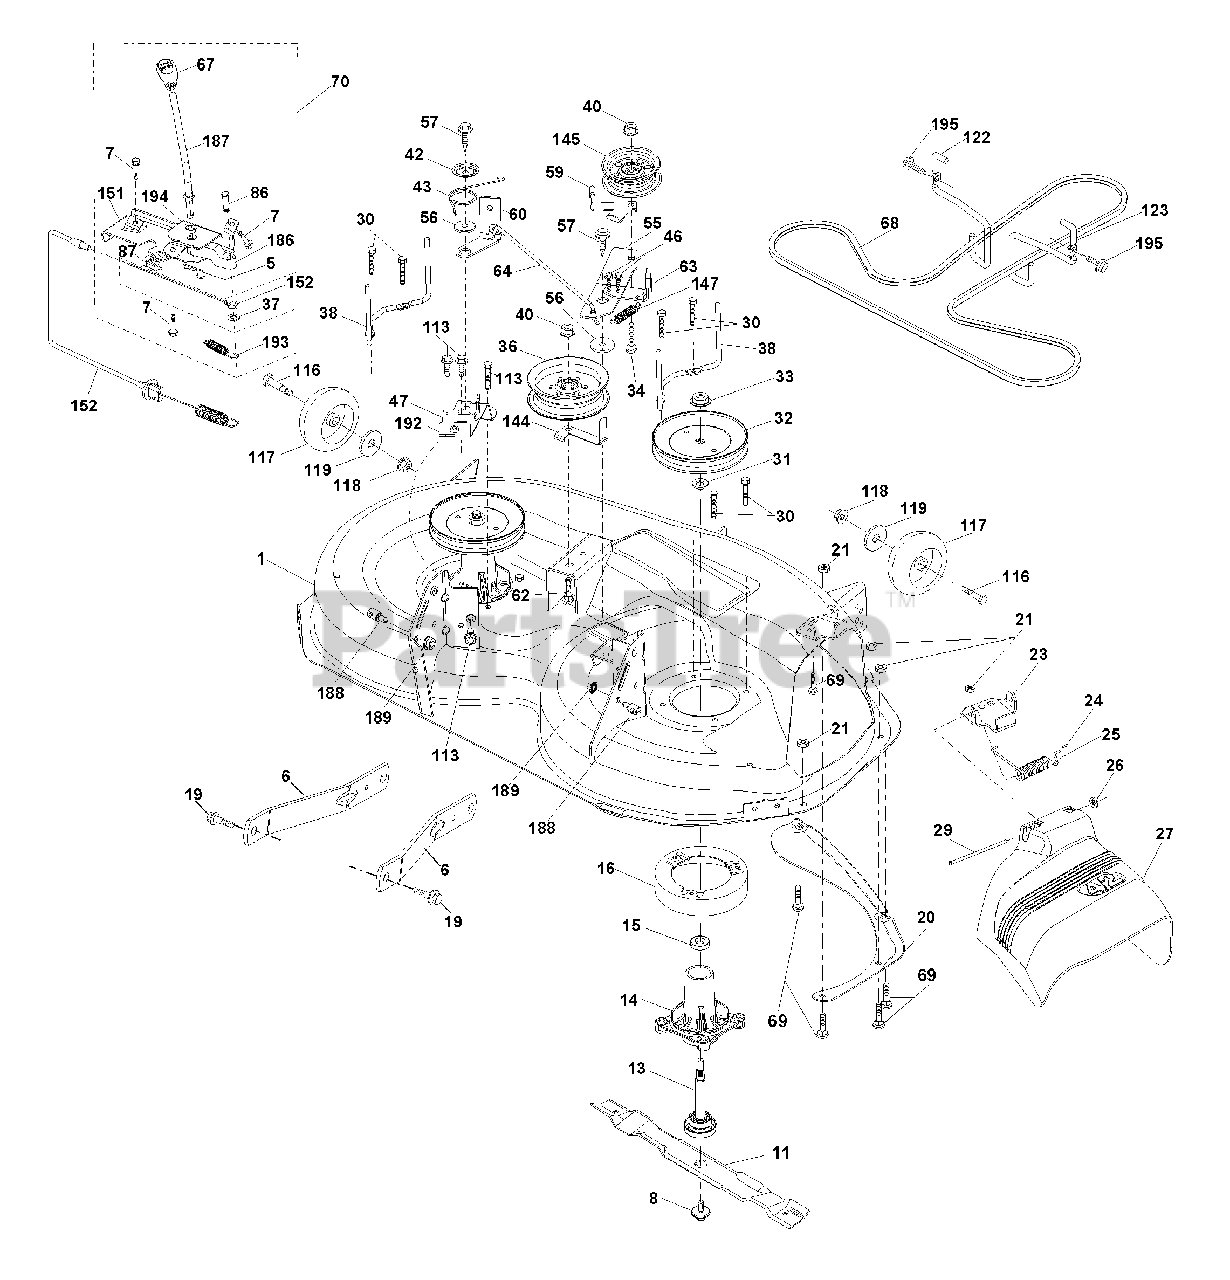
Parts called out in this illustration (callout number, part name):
1	Mower Housing
5	Retainer Spring
6	Arm Suspension
7	Screw 10 x 3/4 Single Hex
8	Bolt/Washer asm 7/16-20 unf
8	Blade, 42" Mulching Premium
11	Blade, 42" Hi-Lift
11	Blade, 42" Mulching Std
13	Shaft Assembly, Mandrel
14	Housing, Mandrel
15	Bearing, Ball, Mandrel
16	Stripper, Mower Deck
19	Bolt, Shoulder
20	Baffle, Vortex
21	Nut, Crownlock 5/16-18 unc
23	Bracket, Deflector
24	Cap, Sleeve
25	Spring, Torsion, Deflector
26	Nut, Push
27	Shield, Deflector
29	Rod, Hinge
30	Screw Thdrol Rolling Wsh Hd
31	Washer, Spacer
32	Pulley, Mandrel
33	Nut, Toplock, Flanged
34	Bolt Carr Sh. 3/8-16 x 1-1/2 Gr. 5
36	Pulley, Idler, Flat
37	Washer 13/32 x 13/16 x 16 Ga.
38	Keeper Belt LH Mandrel
40	Nut, Lock Flg. 3/8-16 unc
42	Spring Torsion Brake
43	Spring Torsion Retainer
46	Screw Thd Roll 1/4-20 x 5/8
47	Bracket Clutch Cable
55	Arm, Idler
56	Spacer, Retainer
57	Screw Hexwsh Thd 3/8-16 x 1
59	Guard, Tuv Idler
60	Arm Brake Mower
62	Bolt Rdhd Sqnk 3/8-16 unc x 2
63	Arm Brake Mower
64	Linkage Brake
67	Handle, Clutch Cable
68	V-Belt
69	Bolt Rdhd Sqnk 5/16-18 x 5/8
70	Clutch Asm. Manual
86	Pin Attachment Cable
87	Switch Interlock
113	Screw 5/16-18
116	Bolt
117	Wheel Gauge
118	Nut Lock 3/8-16 UNC
119	Washer 3/8-7/8 x 14 Ga.
122	Keeper Belt Eng. LH
123	Keeper Belt Eng. RH
144	Keeper Belt
145	Pulley Idler
147	Spring Return
151	Bracket Clutch CBL
152	Cable Clutch Manual w/Spr.
186	Arm Acutator CL Cable
187	Lever Control CL Cable
188	Stud Fastener
189	Nut Lock Hex Flange
192	Bracket Brake Stand LH
193	Spring Plunger Actuator
194	Bearing Control Lever Clutch
195	Screw Hexwsh Thdr 3/8-16 x 3/4
195	Mandrel Assembly
195	Replacement Mower, Complete
